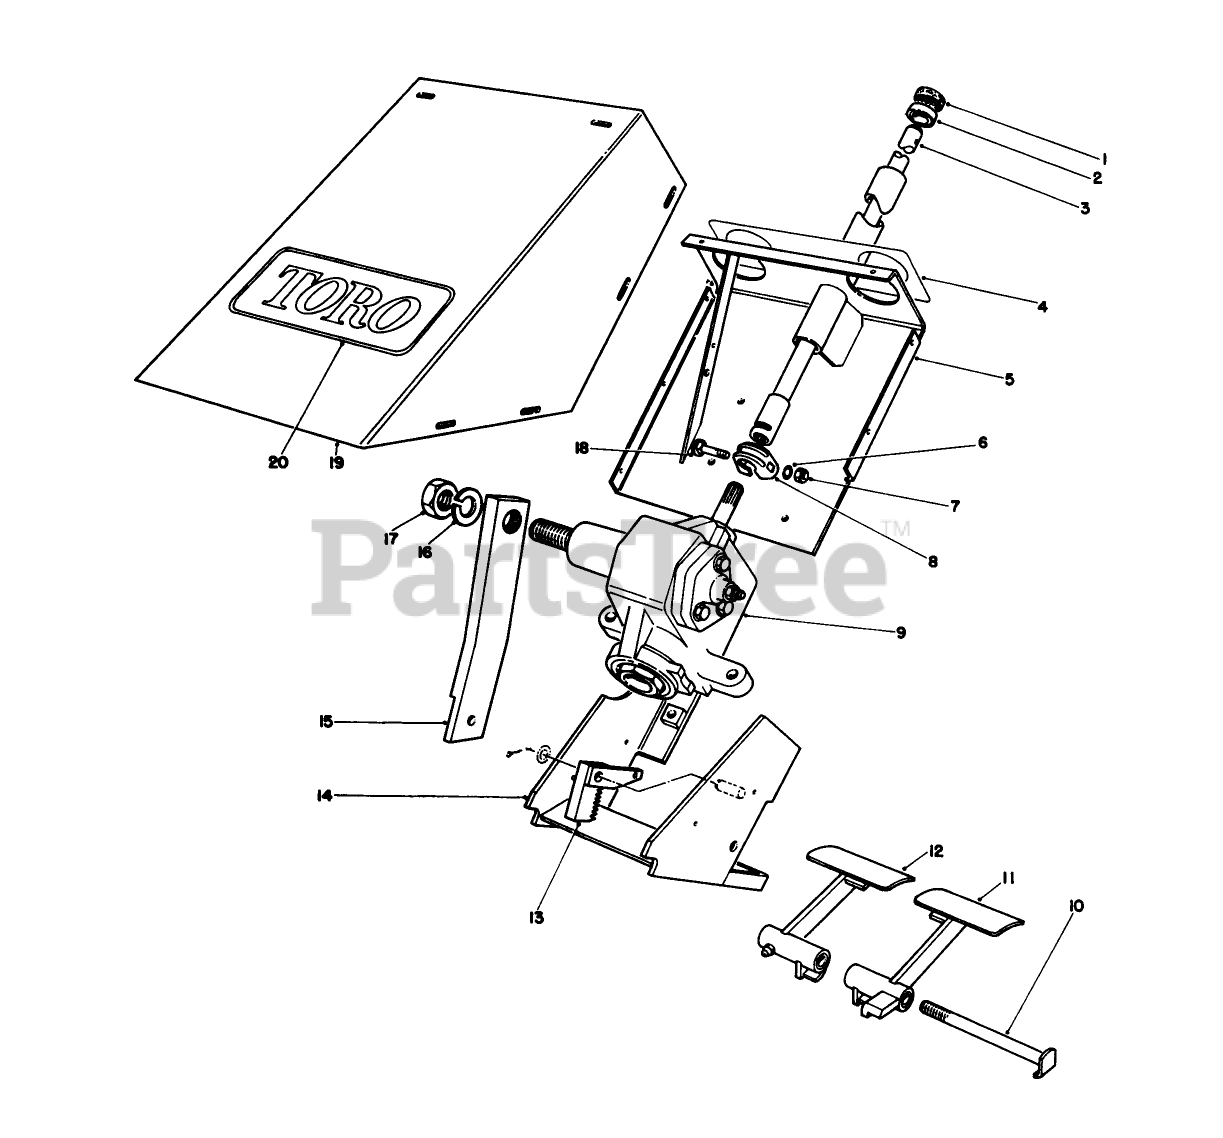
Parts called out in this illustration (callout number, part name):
1	COVER-DUST
2	BALL BRG
3	Shaft-Steering
4	INSTRUCTION DECAL
5	Steering Post
6	WASHER-LOCK
7	NUT-HEX
8	STRG COUPLING CLAMP
9	Steering Gear
10	Pin
11	Brake Pedal L.H.
12	Brake Pedal R.H.
13	Rack
14	Steering Tower
15	Pitman Arm
16	WASHER-LOCK/SP
17	NUT-JAM
18	7/16-14 X 1-3/4 BOLT
19	Tower Cover
20	Decal
